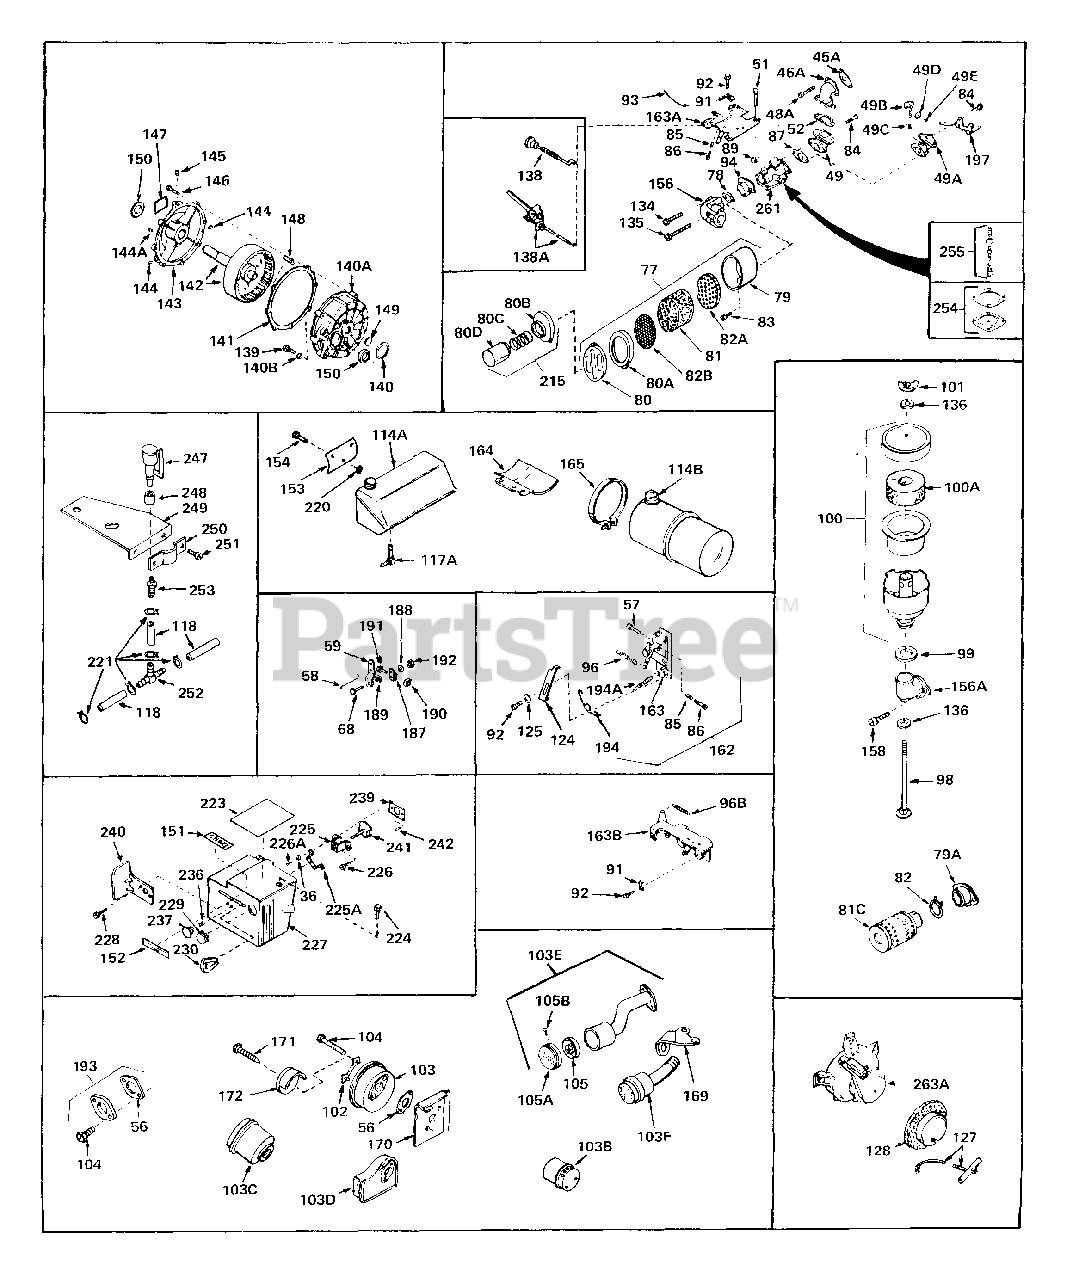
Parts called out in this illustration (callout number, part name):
36	Lockwasher
45A	Gasket, Intake pipe (1/8" thick)
48A	Screw, Fil. flex hd. self-locking, 1/ 4-20 x
51	Screw, Fil. flex hd. self-locking, 1/ 4-20 x
56	Gasket, Exhaust
57	Screw, Hex hd. slotted Sems, 10-32 x 3/8
57	Screw, Hex slotted washer hd. Sems, 8 -32 x
57	Screw, Hex hd. Sems, 10-24 x 9/16
58	Link, Throttle
59	Lever, Governor
68	Screw
77	Cleaner Assy., Air
78	Gasket, Air cleaner
80C	Spring, Pre-cleaner bag
80D	Bag, Pre-cleaner
82A	Screen, Air cleaner
83	Screw, Fil. hd. Sems, 10-32 x 3/4
83	Screw, Phil. fil. hd. Sems, 10-32 x 5 /8
83	Screw, Rd. phil. hd., 10-32 x 7/16
83	Screw, Phil. fil. hd. mach., Sems, 10 -32 x
84	Screw, Hex hd. cap, 1/4-28 x 7/8
84	Screw, Hex hd. cap, 1/4-28 x 1
84	Screw, Hex hd. cap, Sems, 1/4-20 x 1
84	Screw, Hex hd. cap, 1/4-28 x 1-1/4
85	Spring, Compression
86	Screw, Slotted fil. hd. Sems, 8-32 x 3/4
86	Screw, Fil. hd. mach., 5-40 x 7/16
86	Screw, Hex hd., 10-32 x 1-5/16" (Dril led
87	Gasket, Carburetor (1/32" thick)
89	Nut & Lockwasher
91	Clip, Conduit
92	Screw, Hex hd. slotted Sems, 10-32 x 3/8
101	Nut, Wing
102	Plate, Muffler locking
103	Muffler
103F	Muffler
104	Screw, Hex hd. cap, 1/4-20 x 2-3/8
104	Screw, Hex hd. cap, 1/4-20 x 2-1/4
104	Screw, Fil slotted hd. Sems, 114-20 x 2-1/2
104	Screw, Hex hd. Sems, 1/4-20 x 1-3/4
104	Screw, Phil. hex hd. Sems, 1/4-20 x 5 /8
104	Screw, Hex hd. cap, Sems, 1/4-20 x 1- 1/2
104	Screw, Hex hd. cap, 1/4-20 x 2-5/16
105	Screen, Muffler
105A	Cover, Muffler
105B	Screw, Hex hd. self-tap, No. 8 x 3/8
117A	Elbow, Fuel fitting
118	Line, Fuel (Braided hose) (8.25")
118	Line, Fuel (Braided hose) (16")
118	Line, Fuel (Braided hose) (32")
134	Screw, Fil. slotted hd. Sems, 10-32 x 3/4
135	Screw, Fil. hd. cross-recessed reach. , 10-32
135	Screw, Pan flex hd., 10-24 x 7/8
136	Washer, Fibre
136	Washer, Paper
138	Control, Throttle
138A	Control, Throttle
140	Gasket, Reducer housing
140A	Housing, Reducer
140B	Lockwasher
141	Gasket, Housing
142	Shaft & Gear Assy.
143	Cover, Housing (All 6:1 gear reductio n
144	Plug, Pipe (All 6:1 gear reduction mo dels)
144A	Plug, Pipe
145	Plug, Pipe
146	Screw
147	Decal, Oil fill
148	Pin, Shaft & Gear (All 6:1 gear reduc tion
149	Plug, Expansion (All 6:1 gear reducti on
150	Seal, Oil (All 6:1 gear reduction mod els)
154	Screw, Phil. hex hd. Sems, 1/4-20 x 5 /8
158	Screw, Fil. slotted hd. Sems, 10-32 x 3/4
162	Control Assy., Mini Bike Speed
169	Bracket, Muffler
170	Baffle, Heat
171	Screw, Hex hd. Sems, 1/4-14 x 7/8
172	Cover, Muffler
193	Kit, Exhaust adapter
215	Kit, Pre-cleaner
220	Spacer, Strip
221	Clamp, Fuel line
224	Screw, Phil. pan hd. self-tap, 10-32 x 5/16
228	Screw, Phil. pan hd. Sems, 8-32 x 5/1 6
229	Plug, Cover
230	Knob, Control
236	Spring, Primer knob
237	Knob, Primer
241	Plate Assy., Choke
242	Screw, Flat trim hd. mach. , 10-32 x 7/16
260	Condenser
